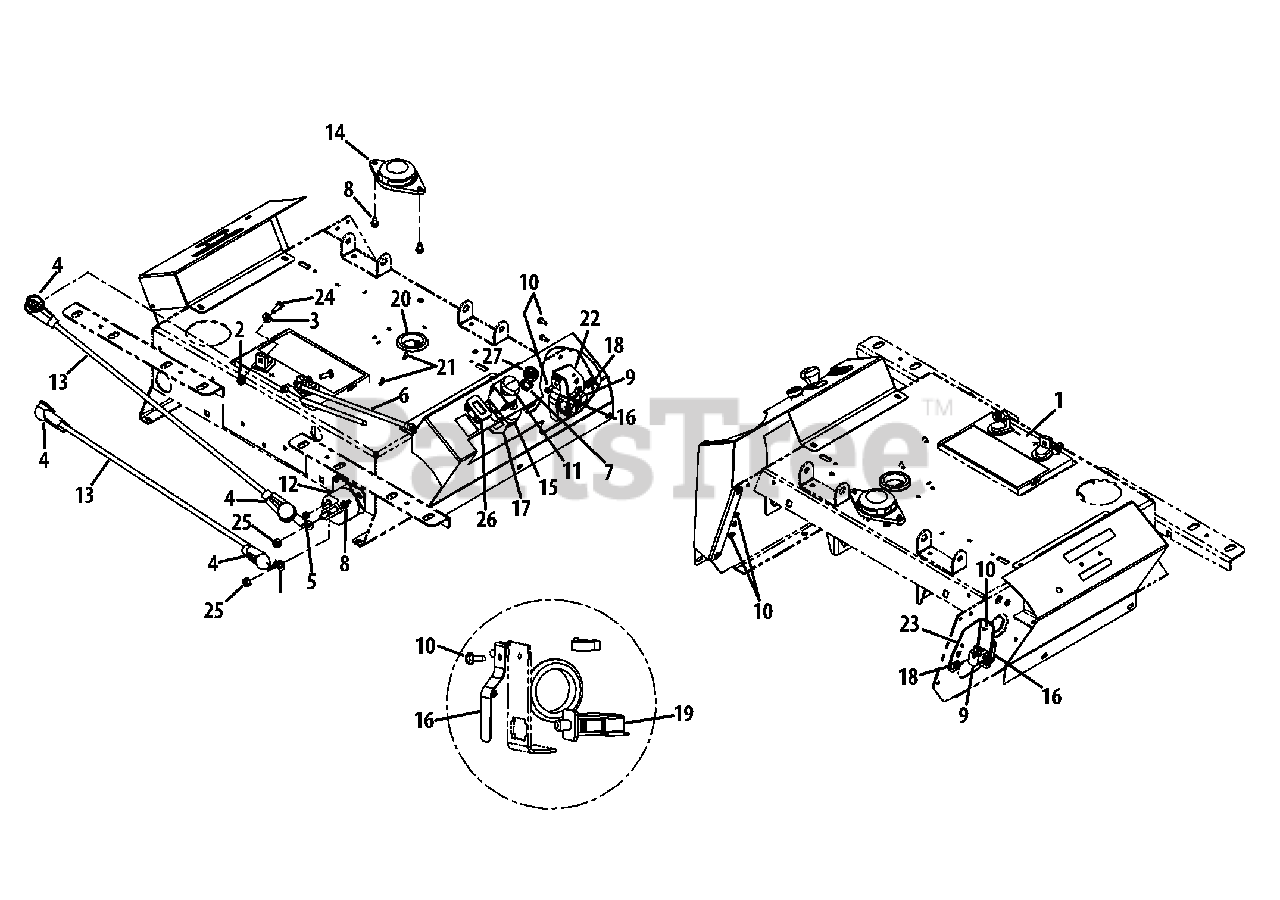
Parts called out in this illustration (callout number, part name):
2	Nylock Nut, 1/4-20
3	Flat Washer, .271 x .630 x .065
4	Boot Terminal, 1.00 x 2.50
5	Nylock Nut, #10-32
6	Battery Cable
7	Nut, Ignition Switch, 5/8-32
8	Hex Flange Screw, 1/4-20 x .500
10	Flange Screw, #10-24 x .500
11	PTO Switch
13	Battery Cable
14	Seat Switch
15	Ignition Switch
16	Renovator Spring
17	PTO Bracket
18	Nut, #10-24
19	Delta Switch
20	Grommet, 1/8 x 1.5 x 2.13
21	Electric CDT Clip
22	RH Deck Switch Mount Bracket
23	LH Deck Switch Mount Bracket
24	Hex Screw, 1/4-20 x .75
25	Hex Lock Nut, 5/16-18
27	Ignition Switch Cap
